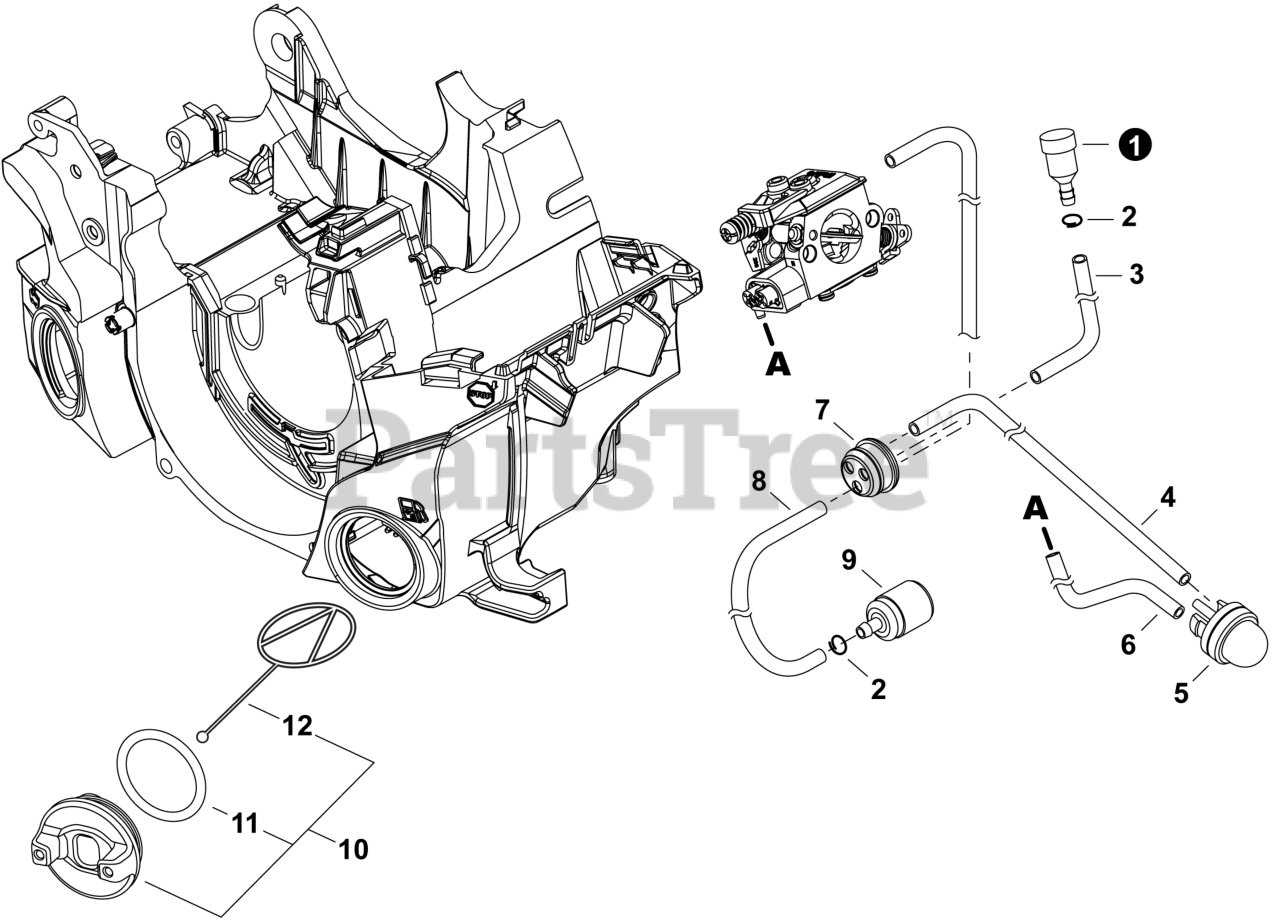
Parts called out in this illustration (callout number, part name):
1	VENT ASSY
3	PIPE, FUEL 3x5x70 BLACK
4	PIPE, PURGE 2.4x5x140 BLACK
5	BULB, PURGE
6	PIPE, FUEL 2.4x5x105 BLACK
7	GROMMET, FUEL 5
8	PIPE, FUEL 3x5x210 BLACK
9	FILTER, FUEL
10	CAP ASSY, FUEL
11	O-RING 29
12	CONNECTOR, CAP L= 60 MM
